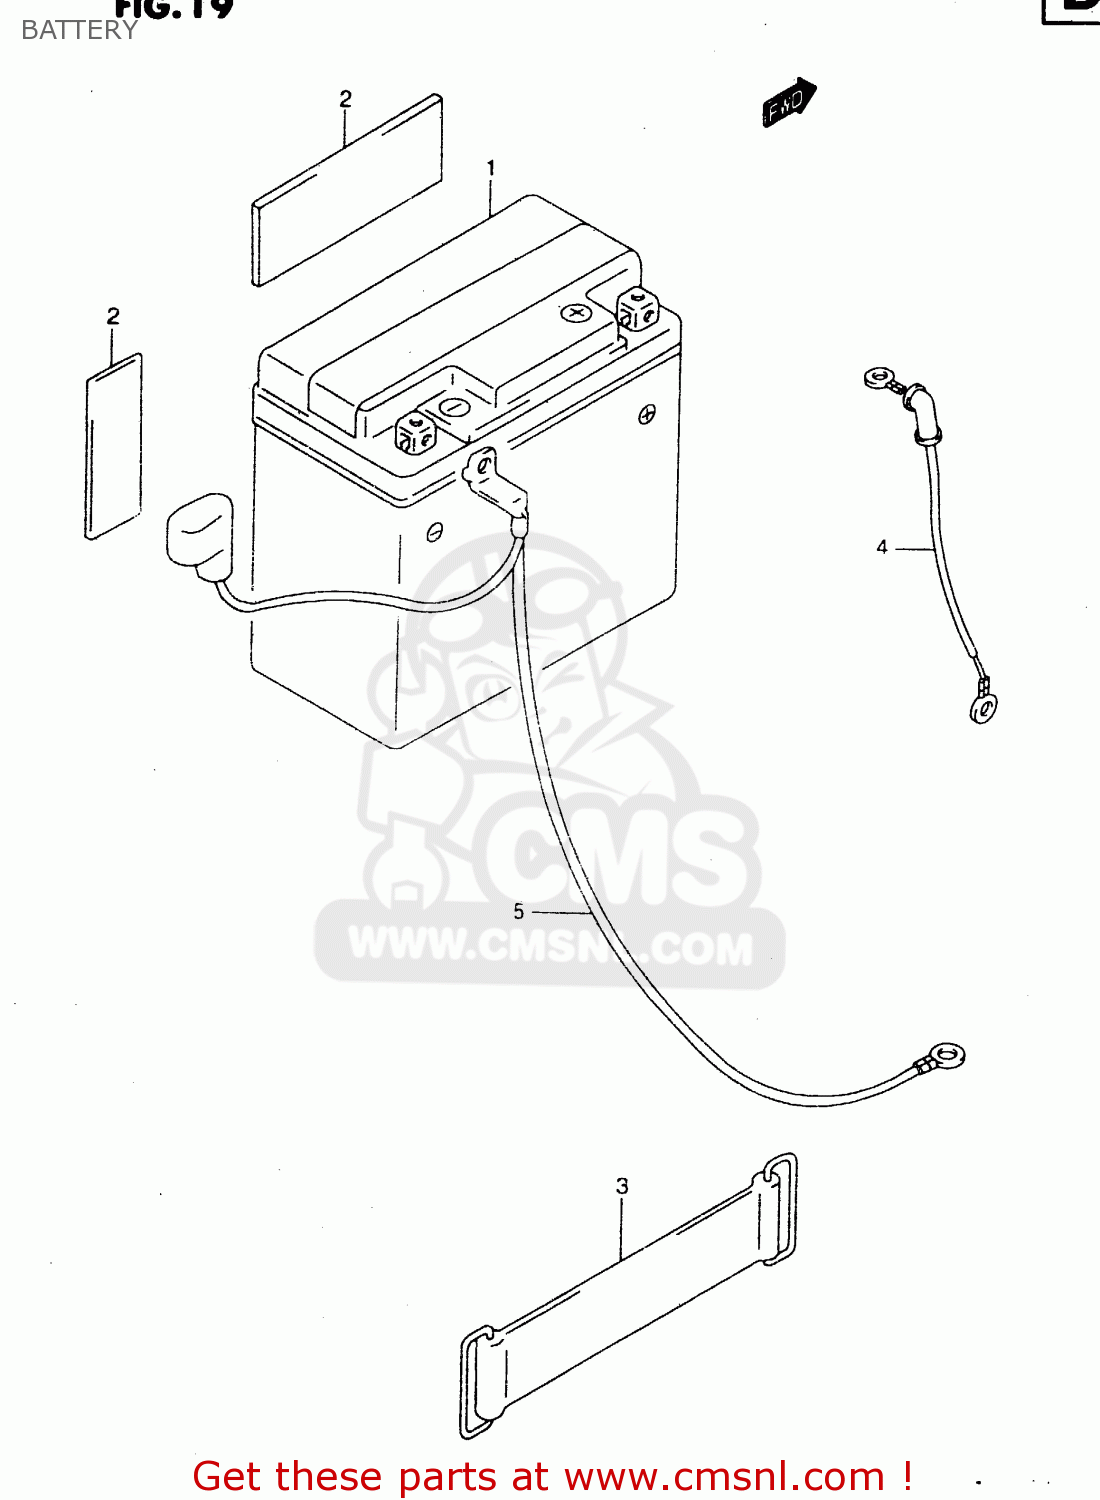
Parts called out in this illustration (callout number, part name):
1	BATTERY ASSEMBLY (12V) FTX
2	PROTECTOR(170X95X3.0)
3	BAND
4	WIRE,BATTERY PLUS LEAD
5	WIRE,BATTERY MINUS
